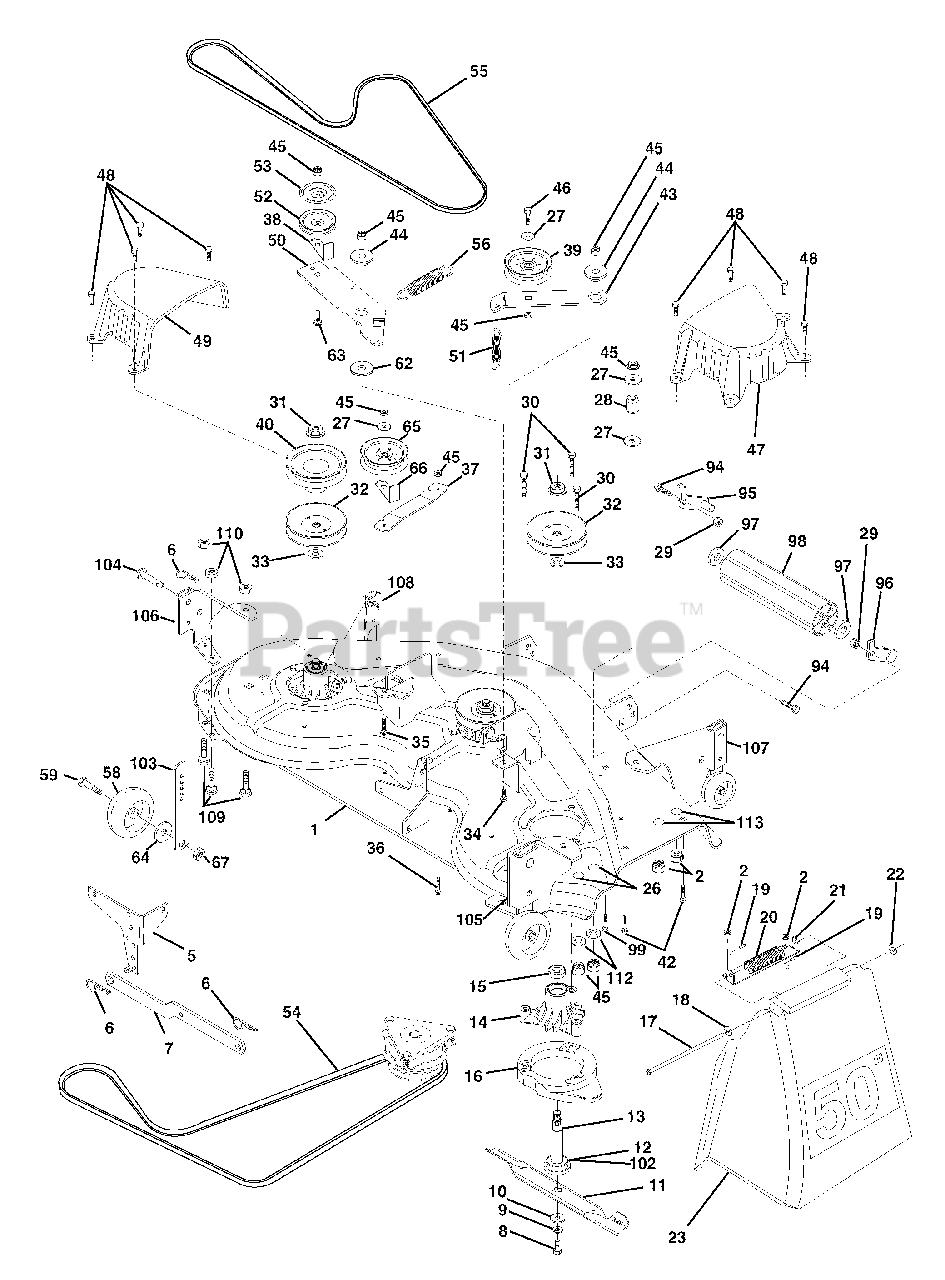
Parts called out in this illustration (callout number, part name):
1	Deck Asm., Mower 50" Vented
2	Nut, Crownlock 5/16-18
5	Bracket Asm., Sway Bar
6	Retainer,Spring
7	Arm Suspension, Rear
8	Bolt 3/8-24 x 1.25 Gr. 8 Patched
9	Washer, Lock Hvy 3/8 Unplated
10	Washer, Hard Blade Mower Vented
11	Blade (3 Required)
12	Bearing, Ball #6204
13	Shaft Asm., W/Lower Brg
14	Housing, Mandrel 50" Vent
15	Bearing, Ball Mandrel
16	Stripper, Mower Vented
17	Rod,Hinge
18	Washer 11/32 x 5/8 x 16 Ga.
19	Cap Sleeve
20	Spring, Torison Deflector
21	Bracket, Deflector
22	Nut, Push
23	Shield, Deflector Mower
25	Washer 11/32 x 3/4 x 16 Ga.
26	Bolt Rd Hd Sht Sqnk
27	Washer 13/32 x 13/16 x 16 Ga.
28	Spacer, Spring Stop Idler
29	Nut, Lock Hex W/Wsh 3/8-16 Unc
30	Screw Thd Rolling Washer Head
31	Nut, Flg Top Lock Cntr 9/16
32	Pulley, Mandrel
33	Washer, Spacer Mower Vented
34	Bolt, Carriage 3/8-16 x 1-1/4
35	Bolt, Carriage 3/8-16 x 2
36	Bolt, Carriage 3/8-16 x 1 Gr. 5
37	Stiffener, Arm Idler
38	Keeper, Belt Idler
39	Pulley, Idler Flat
40	Pulley, Driven
42	Bolt, Carriage 5/16-18 Unc x 3/4
43	Arm, Idler Secondary
44	Spacer, Retainer
45	Nut, Crownlock 3/8-16 Unc
46	Bolt, Fin Hex 3/8-16 Unc x 1-3/4
47	Cover, Mandrel RH
48	Screw, Thd Roll 1/4-20 x 5/8
49	Cover, Mandrel LH
50	Arm, Idler Primary
51	Spring, Secondary
52	Pulley, Idler V Groove
53	Shield, Idler
54	V-Belt, Mower Primary
55	V-Belt, Mower Secondary
56	Spring, Primary
58	Wheel,Gauge
59	Bolt, Shoulder
62	Washer Hardened
63	Bolt Carriage 3/8-16 x 1-1/2
64	Washer 3/8 x 7/8 x 14 Ga.
65	Pulley Idler Flat Mower
66	Keeper, Belt Idler 50" Vent
67	Nut, Center Lock 3/8-16
94	Bolt H 3/8-16 x 1
95	Bracket, Asm. Noseroller LH
96	Bracket, Asm. Noseroller RH
97	Washer 17/32 x 7/8 x 16 Ga.
98	Roller, Nose
99	Bolt, Carriage 3/8-16 x 1-3/4 Gr. 5
102	Washer Felt
103	Bar Adj. Gauge Wh.
104	Pin Head Rivot
105	Bracket Ga Wh Asm RH 50
106	Bracket Ga Wh Asm LH 50
107	Bracket Ga Wh Assy F RH 50
108	Bracket Ga Wh Assy F LH 50
109	Bolt Carriage 5/16- 18 x 5/8
110	Nut Crownlock 5/16-18
112	Washer 17/32 x 3/4 x 16 Ga.
113	Bolt Carriage 5/16-Unc 1/2
